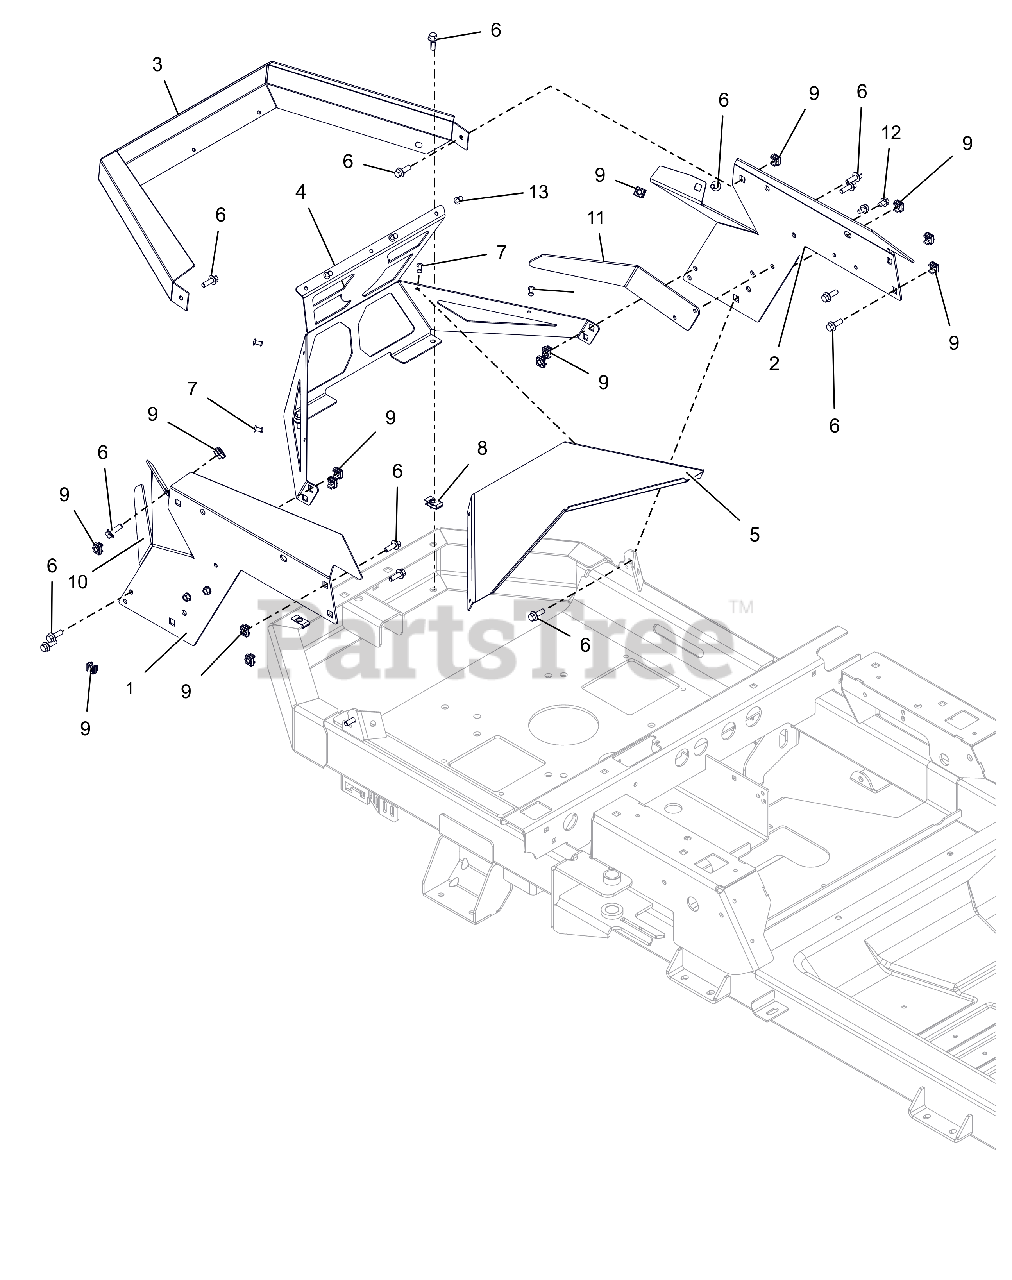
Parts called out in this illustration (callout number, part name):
1	PANEL, RIGHT REAR FENDER MOUNT
2	PANEL, LEFT REAR FENDER MOUNT
3	GUARD, ENGINE WRAP
4	GUARD, ENGINE
5	BAFFLE,ENGINE WRAP
6	BLT,HEX-FLG .25-20X.75 G5 BFP
7	RVT-POP.187X.527 DOME ST
8	NUT-RTNR .25-20X.56
9	NUT RETNR .25-20
10	SHIELD, RH, ENGINE GUARD VALVE
11	SHIELD, LH, ENGINE GUARD VALVE
12	@SCR-TAP .25-20X.37 HWH YWZ TR
13	RIVET, #66 STEEL POP PD BLACK
